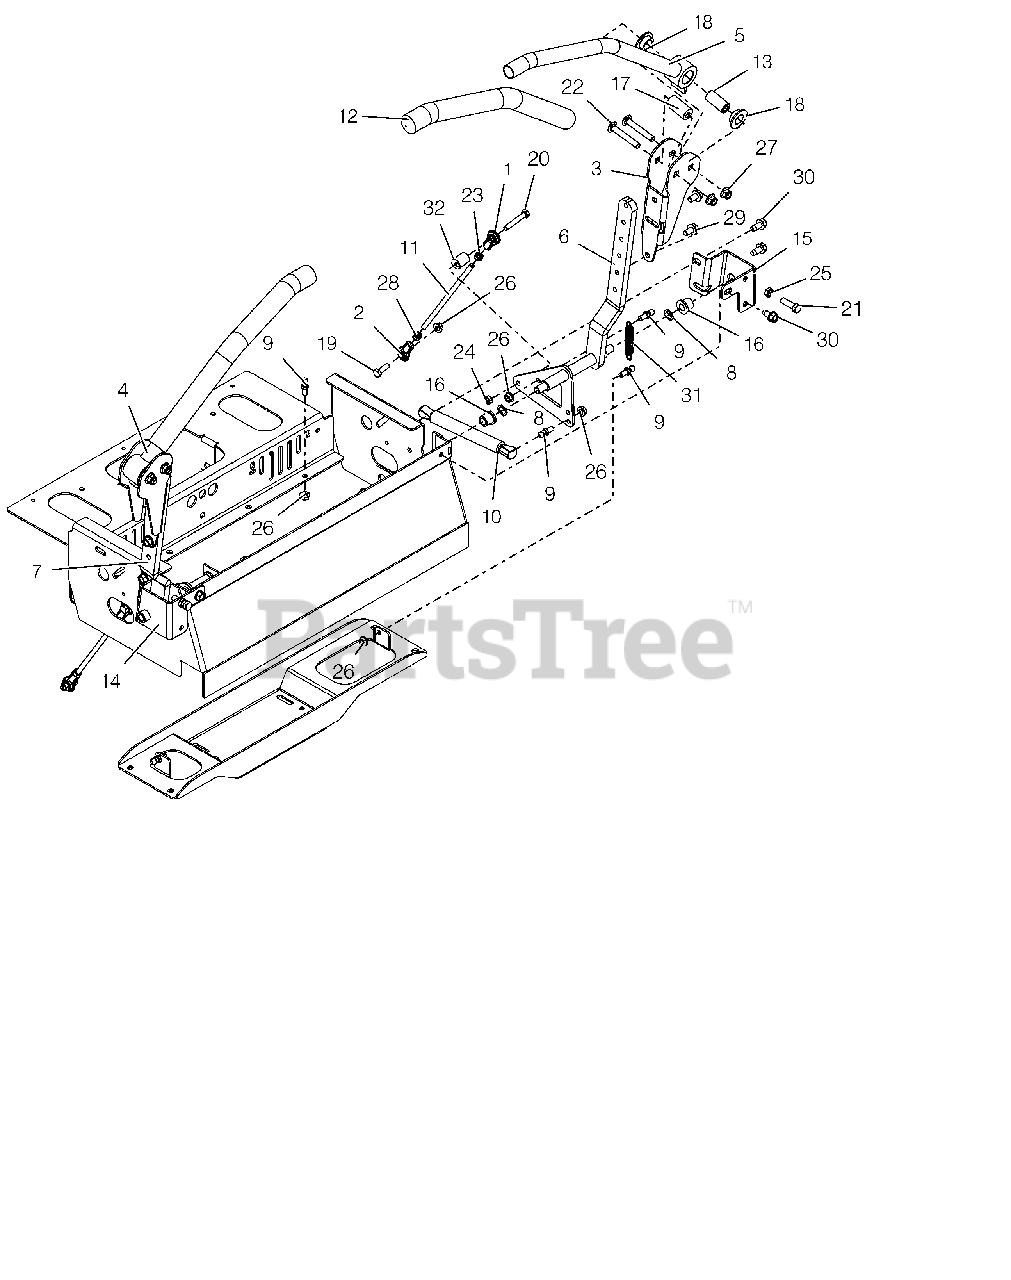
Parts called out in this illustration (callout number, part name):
1	ALIGNABALL, 5/16 RH THREAD
2	ALIGNABALL, 5/16 LH THREAD
3	ADJ UPPER CONTROL ARM BRKT-BLK
4	WLDMT, CONTROL HANDLE- BLK
5	WLDMT, CONTROL HANDLE- BLK
6	WLDMT, LH LOWER CONTROL ARM
7	WLDMT, RH LOWER CONTROL ARM
8	WAVE WASHER .531X.781X.125FH
9	STUD- BALL
10	DAMPER
11	ROD, STEERING
12	GRIP, HANDLEBAR
13	SPACER, STEERING ARM
14	PT200/400 RH CNTRL STP BRK-RED
15	PT200/400 LH CNTRL STP BRK-RED
16	BHSG-FLG .500X.750X.750X.125
17	BSHG, ECCENTRIC.406X.875X1.625
18	BSHG-FLG .762X1.48X.44 NYL
19	@BLT-HEX .31-18X1.00 GR5 YWZC
20	@BLT-HEX .31-18X2.00 GR5 YWZC
21	@BLT-HEX .38-16X1.25 GR5 YWZC
22	BLT-RDHDSQSHK, 38-16X2.50 G5YZ
23	NUT-HEX .312-24 YWZC
24	@NUT-LK-CTR .31-18 YWZC
25	NUT-HEX-JAM .375-16 YWZC
26	@NUT-LK-TOP-FLG .31-18 YWZC
27	@NUT-LK-NYL-FLG .38-16 YWZC
28	NUT-HEX .312-24 LH GR5 YWZC
29	BLT, SCRHFWH .375-16X.625 YWZC
30	@SCR-TAP .38-16X.75 HWH TR YWZ
31	SPRING,EXT,.061X.50X3.0
32	ECCENTRIC
